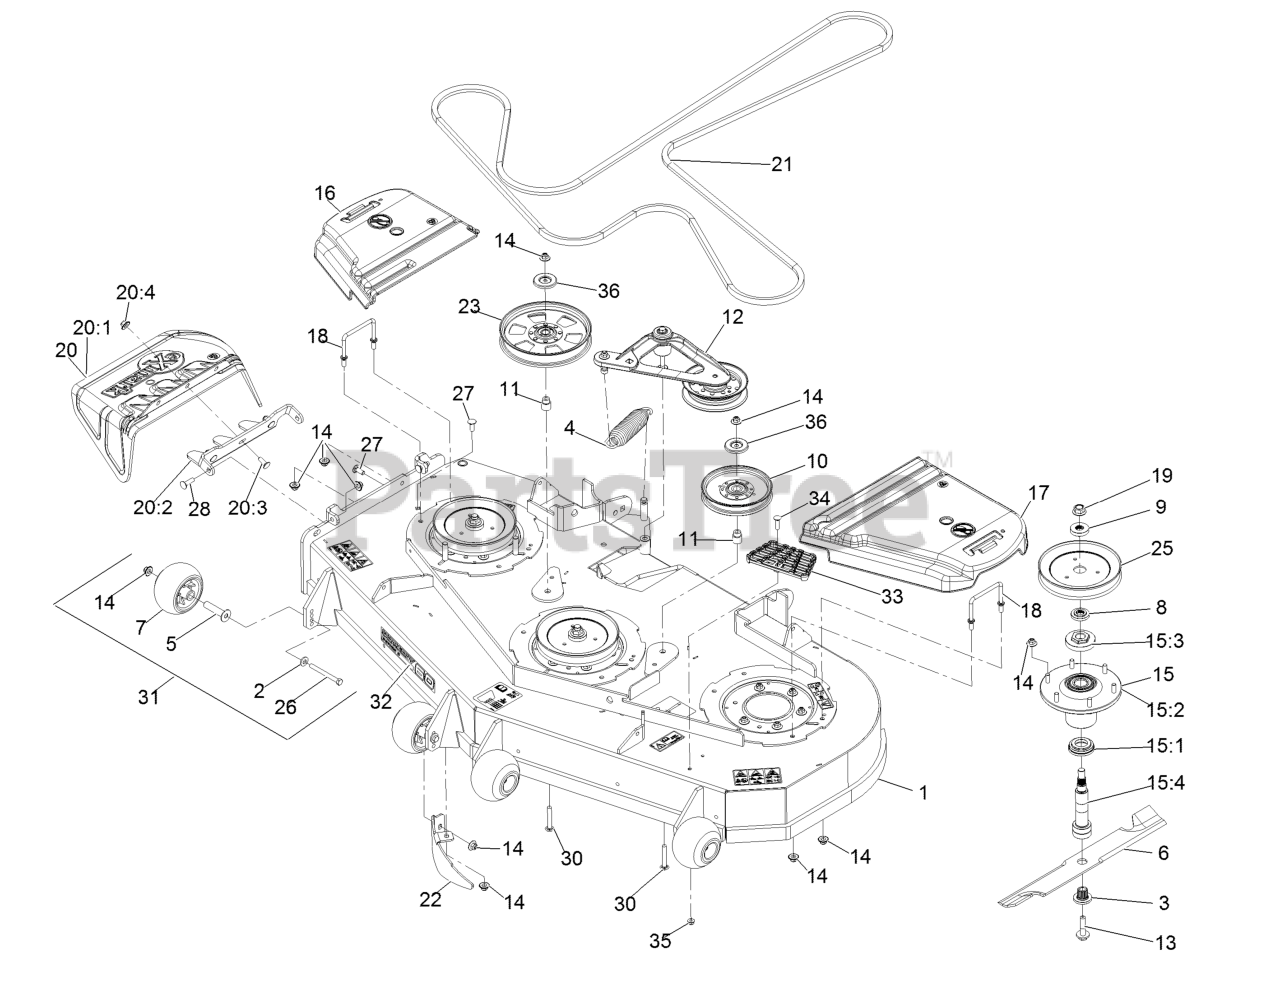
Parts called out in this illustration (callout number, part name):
1	DECK ASM,W/DECALS 60
2	WASHER-BELLEVILLE
3	BUSHING,SPLINED
4	SPRING-EXTENSION
5	AXLE, ROLLER
6	Blade-Extreme 2, 20.50"
7	ROLLER-SCALP, ANTI
8	SPACER,SPLINED STEPPED
9	SPACER,SPLINED
10	IDLER-PULLEY
11	BUSHING-IDLER
12	DECK IDLER ASM
13	SCREW,SEMS 1/2-20 X 2.19
14	Nut-Nyloc 3/8-16 Flg
15	ASM,SPINDLE HOUSING
15:1	GUARD,BOTTOM
15:2	ASM,CUTTER HOUSING
15:3	NUT, SPINDLE 7/8-14
15:4	SPINDLE,DOUBLE SPLINE
16	COVER-BELT, RH
17	COVER-BELT, LH
18	WIREFORM-COVER
19	NUT-FLANGE, CENTERLOCK
20	ASM,DISCHARGE CHUTE
20:1	CHUTE,DISCHARGE
20:2	BRACKET,DISCHARGE CHUTE
20:3	SCREW-CARR
20:4	Nut-Nyloc 3/8-16 Flg
21	BELT,V-5V-198.75
22	DOGLEG - LZ60
23	PULLEY-IDLER, FLAT
25	SHEAVE,BLADE DRIVE 7.25
26	SCREW-HH 3/8-16 X 3 3/4 GR 8
27	SCREW-CARR
28	Bolt-Carriage 3/8-16 X 1 1/4
30	SCREW-CARR
31	KIT, ANTI-SCALP ROLLER
32	DECAL, 606
33	STEP-DECK
34	Bolt-Carriage 5/16-18 X 1 1/4
35	NUT-HF, NI
36	SHIELD-DUST
